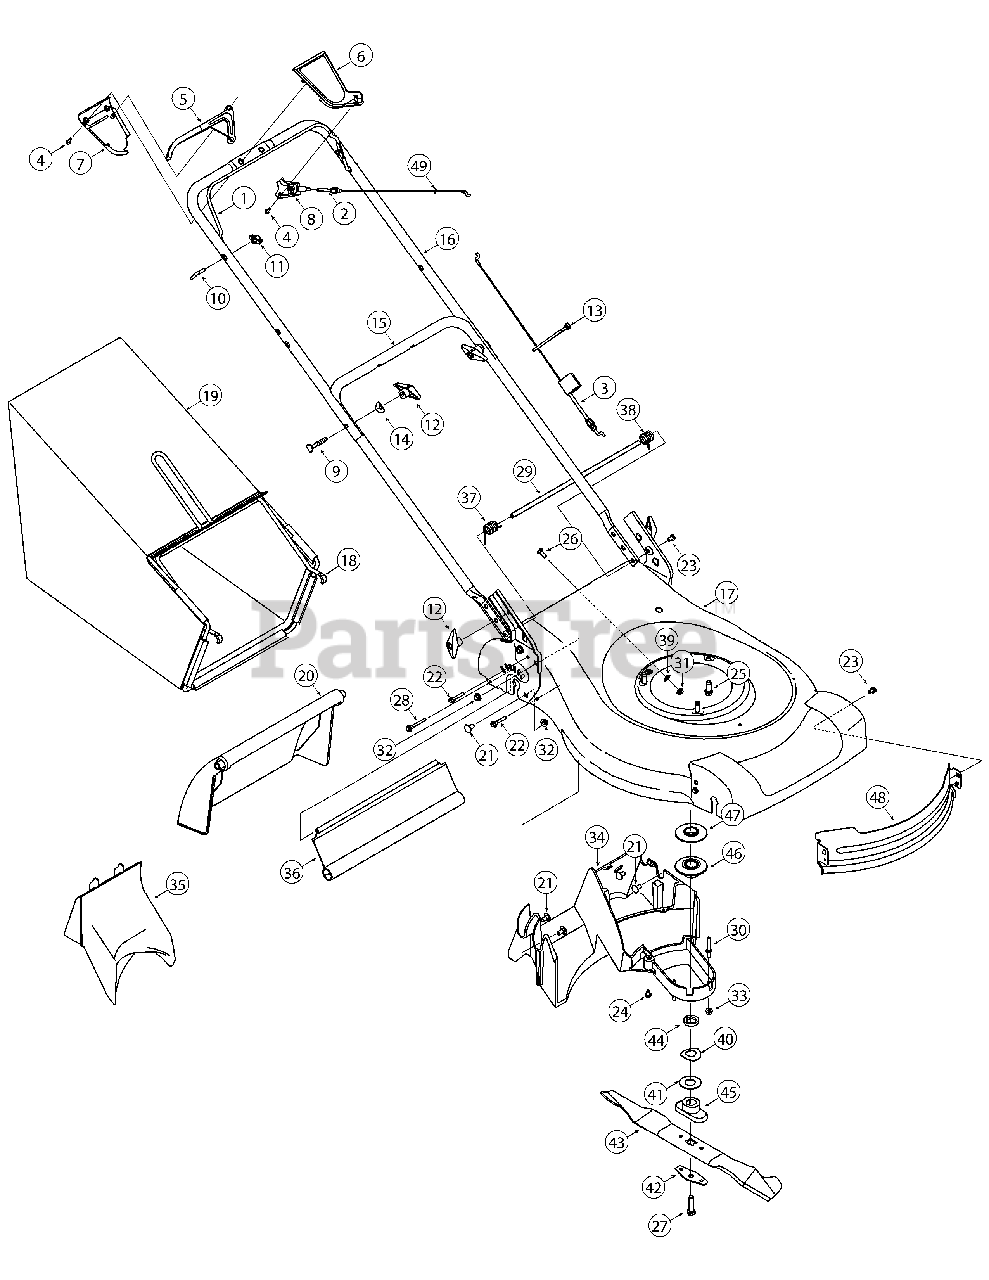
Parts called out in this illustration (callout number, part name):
2	Drive Cable
3	Control Cable
4	Screw, #10-16 x .625
5	Drive Control Lever
6	Upper Control Cover
7	Lower Control Cover
8	Mounting Cap
9	Carriage Bolt, 5/16-18 x 2.0
10	Eye Bolt
11	Wing Nut
12	Handle Knob
13	Cable Tie
14	Saddle Washer, .320 x .93
20	Rear Door
21	Carriage Bolt, 5/16-18 x .62
22	Screw, 1/4-15 x 1.00
23	TT Screw, 1/4-20 x .500
24	TT Screw, 1/4-20 x .375
25	Screw, 3/8-16 x 1.00
26	Carriage Screw, 1/4-20 x .75
27	Screw, 3/8-24 x 1.50
28	Screw, 1/4-20 x 2.00
29	Door Pivot Rod
30	Belt Guard Pin
31	Flange Lock Nut, 1/4-20
32	Flange Lock Nut, 5/16-18
33	Flange Lock Nut, 1/4-20
34	Deck Baffle
35	Mulch Plug
36	Trailshield
37	Door Torsion Spring - RH
38	Door Torsion Spring - LH
39	Flat Washer, .25 x .630 x .0515
40	Spring Washer, .890 x 1.70 x.048
41	Flat Washer, .885 x 1.850 x .060
42	Blade Bell Support
43	21" Mulching Blade
44	Engine Spacer
45	Blade Adapter
46	Lower Engine Pulley
47	Upper Engine Pulley
48	Front Deck Baffle
49	Rubber Gromet
